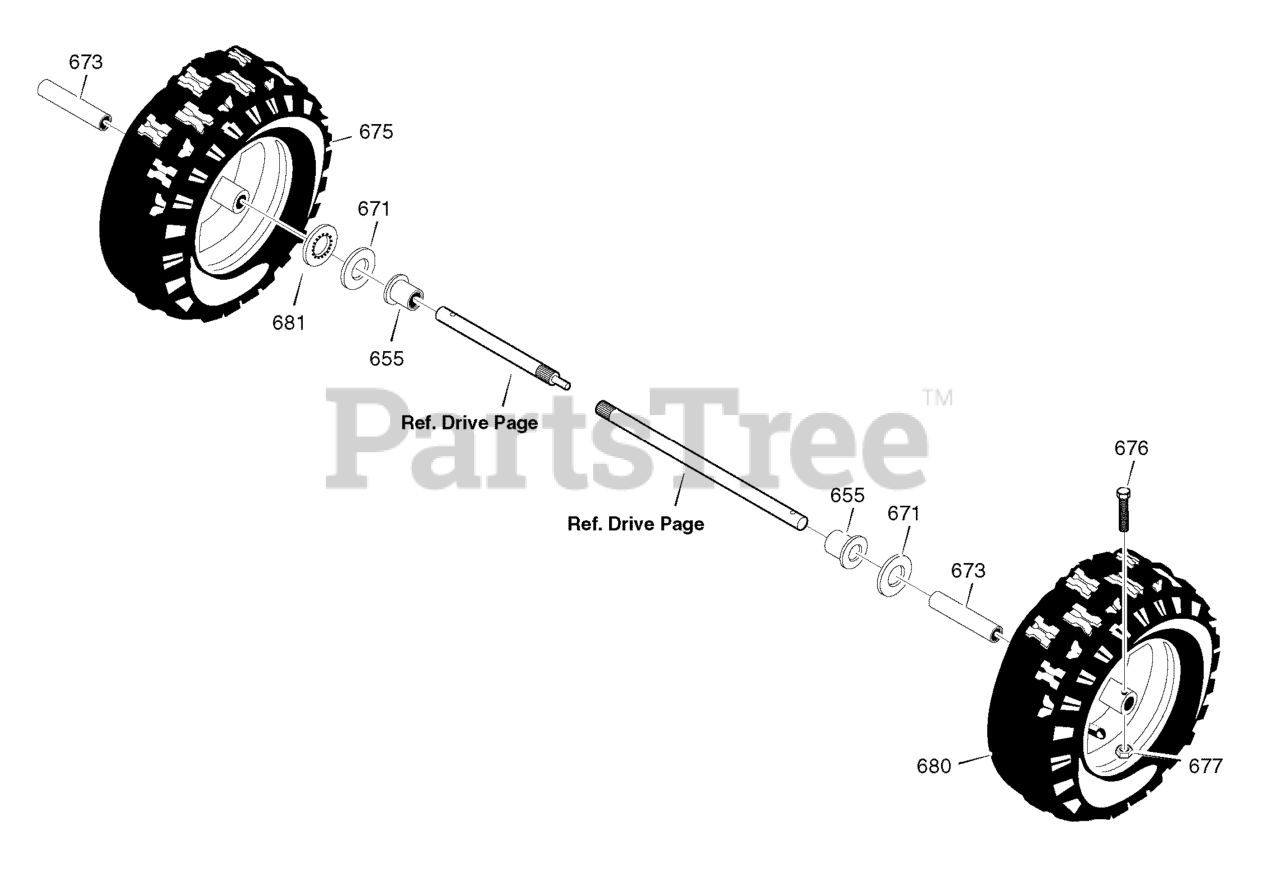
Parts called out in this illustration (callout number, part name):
655	BEARING, AXLE
671	FLATWASHER
673	BUSHING, WHEEL
675	TIRE & RIM, LEFT
676	SCREW, 1/4-20 X 1.75 HH
677	NUT, 1/4-20 HEX NYLOCK
680	TIRE & RIM, RIGHT
681	RETAINER
